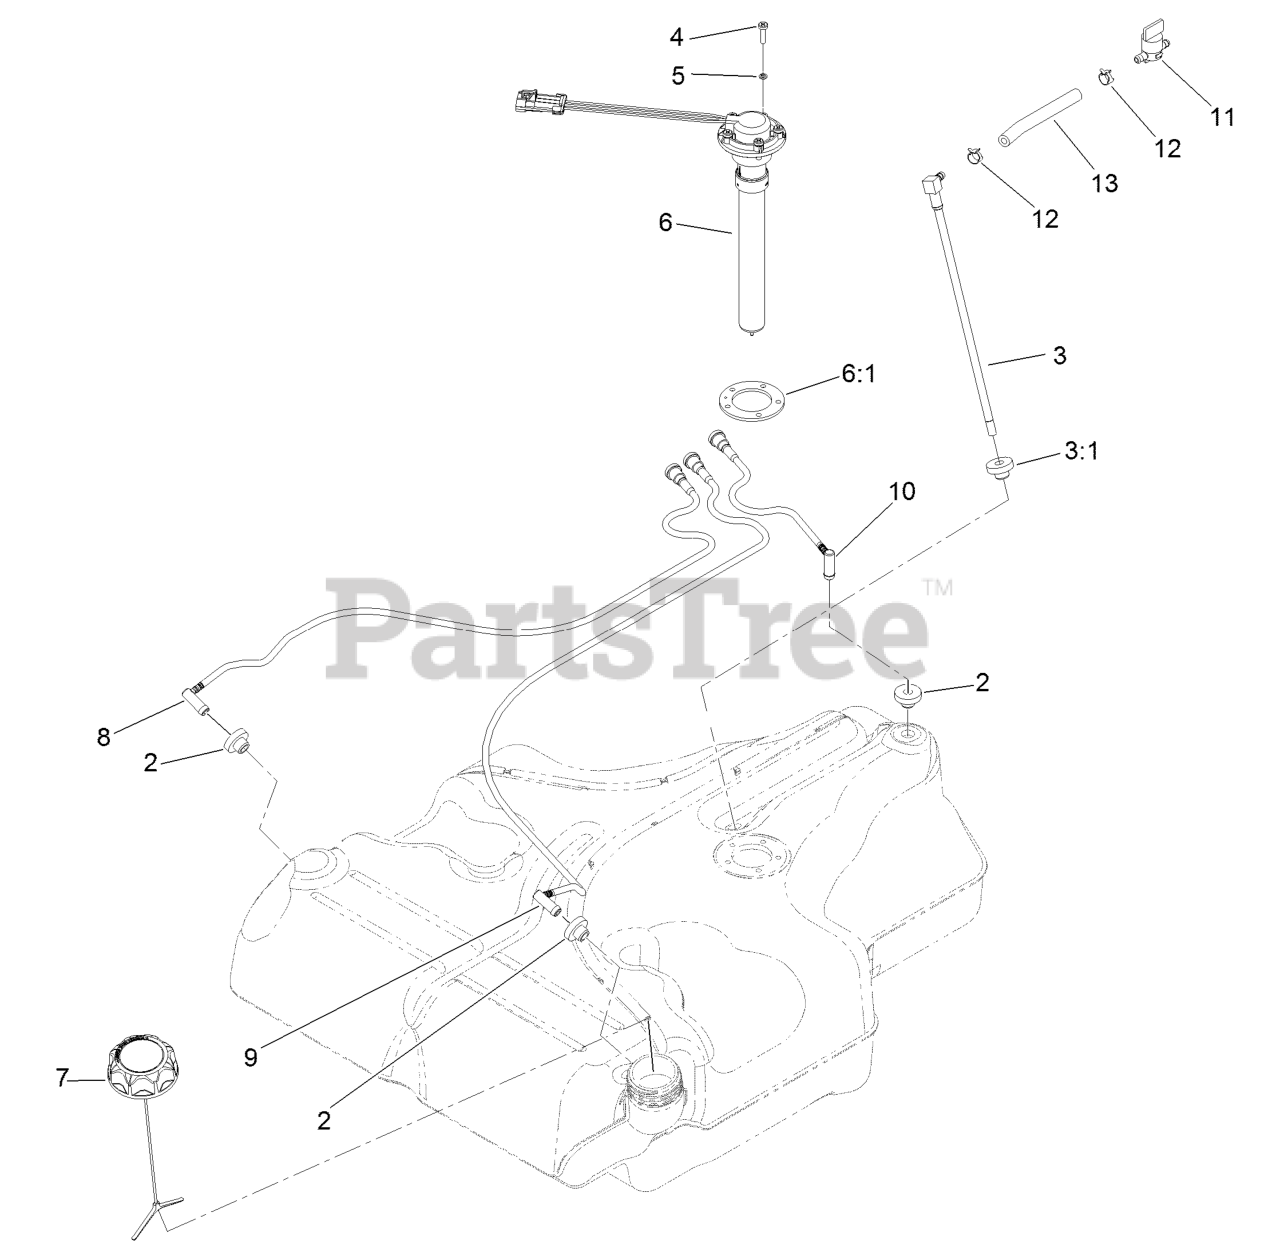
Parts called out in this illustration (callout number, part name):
2	BUSHING
3	FUEL LINE KIT (WITH GROMMET)
3:1	BUSHING
4	SCREW-PAN
5	WASHER-LOCK
6:1	GASKET-SENDER, FUEL
8	RH VENT LINE KIT (WITH GROMMET)
9	LH VENT LINE KIT (WITH GROMMET)
10	REAR VENT LINE KIT (WITH GROMMET)
11	VALVE-FUEL
12	CLAMP-HOSE
13	HOSE-FUEL
